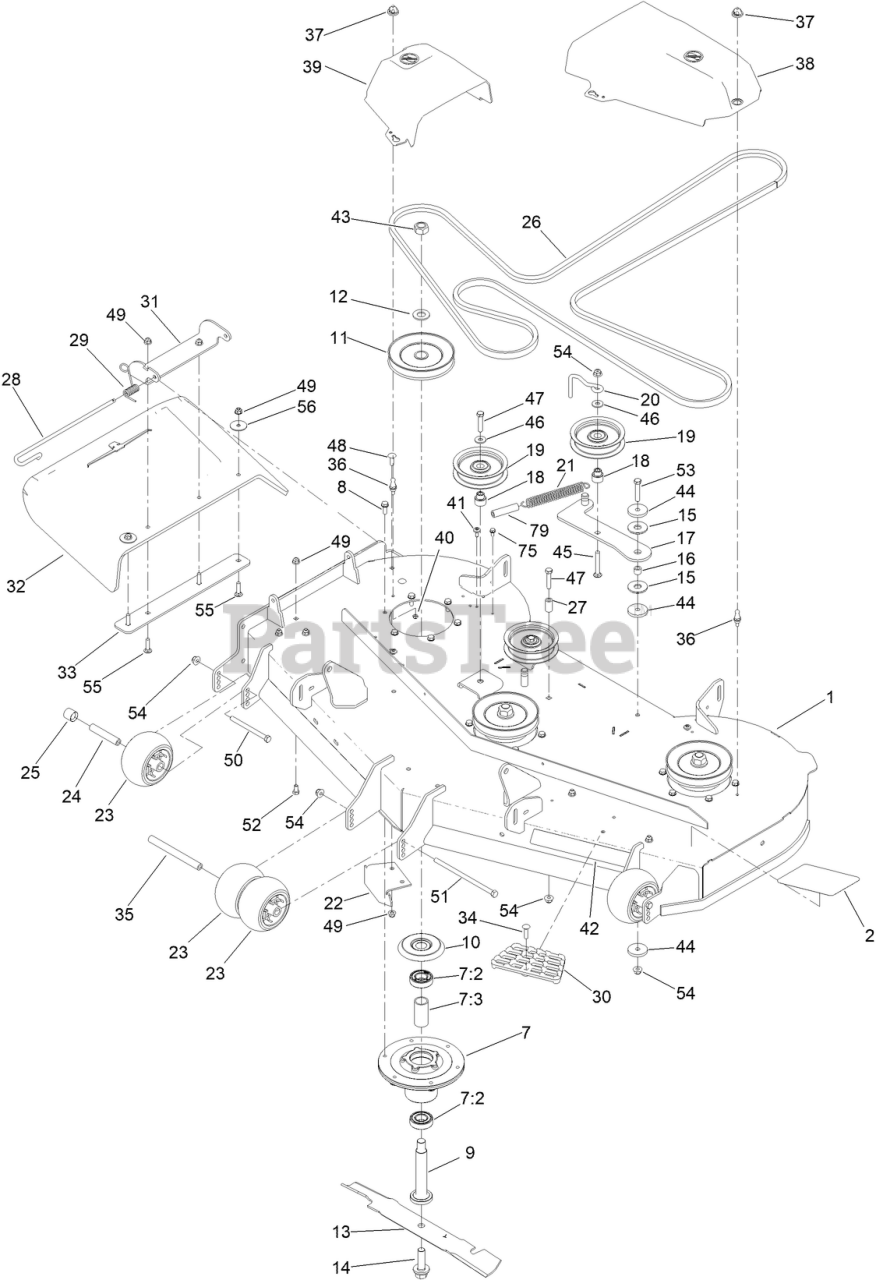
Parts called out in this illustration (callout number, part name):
1	54 IN DECK DECAL ASM
2	DECAL - DECK 54
7	SPINDLE ASM
7:2	BEARING-BALL
7:3	SPACER-BEARING
8	SCREW-TAPTITE
9	SHAFT-SPINDLE
10	SHIELD-BEARING
11	PULLEY
12	WASHER
13	BLADE-HI FLO
14	SCREW-BLADE
15	WASHER-FRICTION, COMPOSITE
16	SPACER
17	IDLER ARM ASM
18	BUSHING-IDLER
19	PULLEY-IDLER, FLAT
20	GUIDE-BELT, IDLER
21	SPRING-EXTENSION
22	BAFFLE-CUTOFF
23	ROLLER-SCALP, ANTI
24	TUBE-SPANNER
25	SPACER-AXLE, REAR
26	V-BELT (B SEC 174.25 EL)
27	SPACER-FENDER
28	PIN-CHUTE
29	STEP-DECK
30	BRACKET-DEFLECTOR, UPPER
31	SPRING-TORSION
32	DEFLECTOR - MOLDED
33	PLATE-DEFLECTOR
34	BOLT-CARRIAGE
35	SPACER-WHEEL
36	STUD-BALL
37	GROMMET-BALL
38	COVER-BELT, LH
39	COVER-BELT, RH
40	NUT-LOCK
41	SCREW-SHOULDER
42	DECAL - IRON FORGED
43	NUT-HEX
44	WASHER-PLAIN
45	SCREW-CARR
46	WASHER-HARDENED
47	SCREW-HH
48	SCREW-CARR
49	NUT-HF, NI
50	SCREW-HH
51	SCREW-HH
52	SCREW-HH
53	SCREW-HH
54	NUT-HF, NI
55	SCREW-CARR
56	WASHER-FLAT
75	SCREW-HWH
79	HOSE-BREATHER
